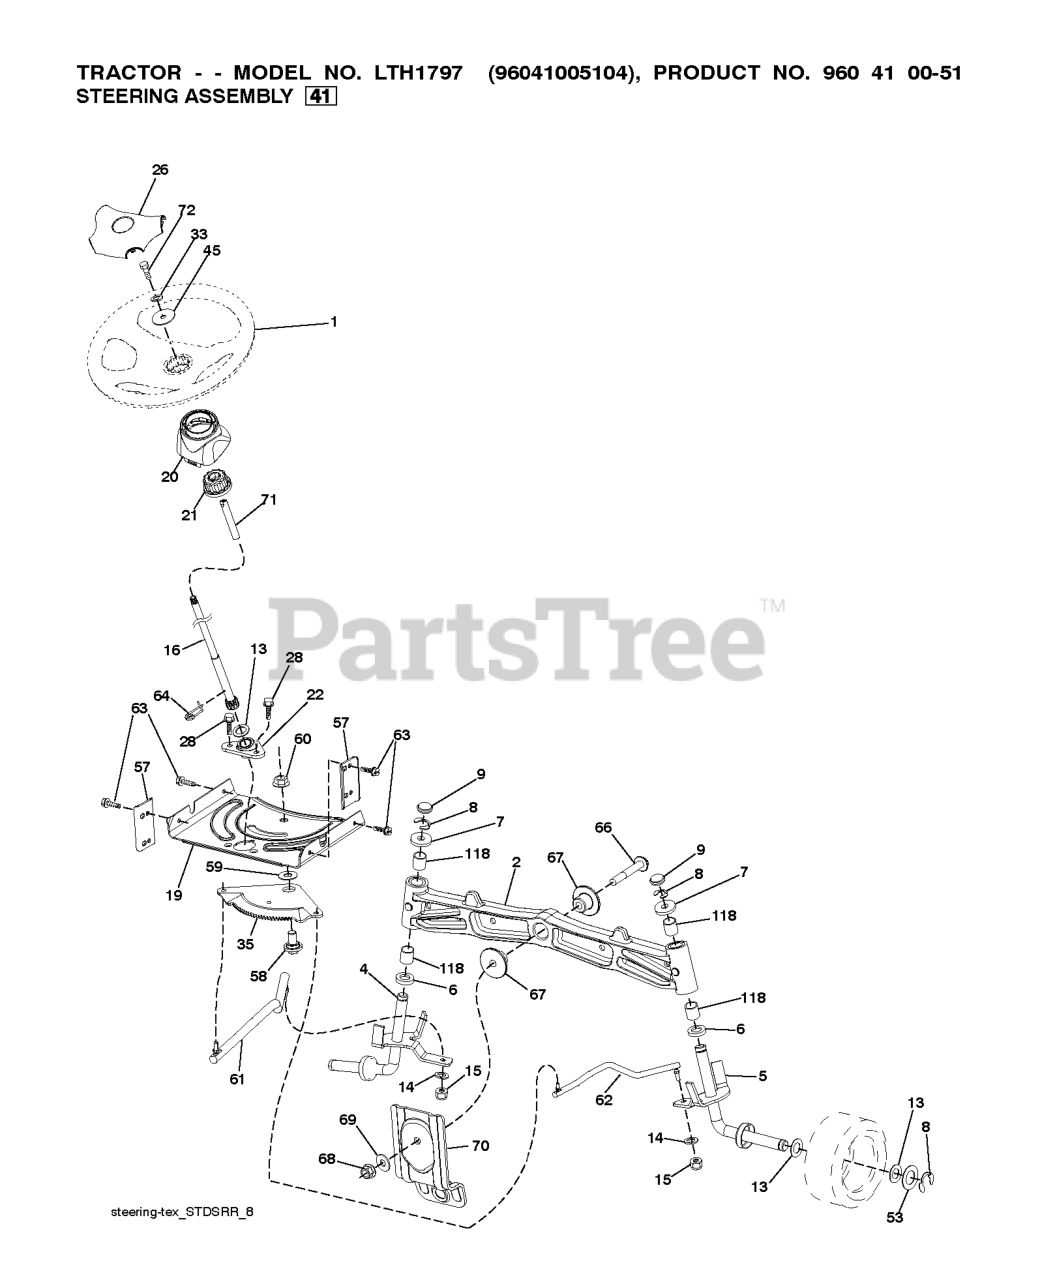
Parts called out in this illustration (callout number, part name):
1	RP WHEEL.STEER.HUSQ.PREM.OVMLD
2	AXLE.SVC.ASM CAST IRON.TEX
4	SPINDLE.WELDED.LH.15"TEX
5	SPINDLE.WELDED.RH.15"T
6	THRUST WASHER
9	CAP.SPINDLE.BLACK
14	WASHER, LOCK 3/8
15	NUT CROWNLOCK 3/8-24
16	SHAFT.STEER.3/4.PLATED.TEX
19	PLATE.STEER.DDL.NLT/NG
20	BOOT, STEERING
21	ADAPTER, WHEEL STNG..
22	STEERING.SUPT.LOWER.
26	RP INSERT.CAP.WHL.STRG.HUSQ.
28	SCREW, 3/8-16X3/4
33	WASHER.LOCK.HVY.HLCL.SPR.5/16
35	GEAR.SECTOR.PLATE.DDL.
45	WASHER.11/32
53	WASHER.HARDENED
57	BRACKET.UPSTOP.TEX
58	BOLT.SHOULDER.SECTOR.P
59	WASHER.THURST.SECTOR.S
60	NUT FLANGE LOCK 5/8-11
61	DRAGLINK.LH.BALLSTUD.D
62	DRAGLINK.RH.BALLSTUD.D
63	SCREW
64	RETAINER.CLIP.SPRING.S
66	BOLT HEX FGHD 7/16-14 X 3 SERR
67	BUSHING.PM.FRONT AXLE
68	NUT.LOCK.FLANGE.7/16
69	WASHER.1.5X.505X.118
70	BRKT.DECK.SUSPENSION.F
71	SHAFT.EXTEN.STRG.SPLINE
118	BUSHING, AXLE CAST
